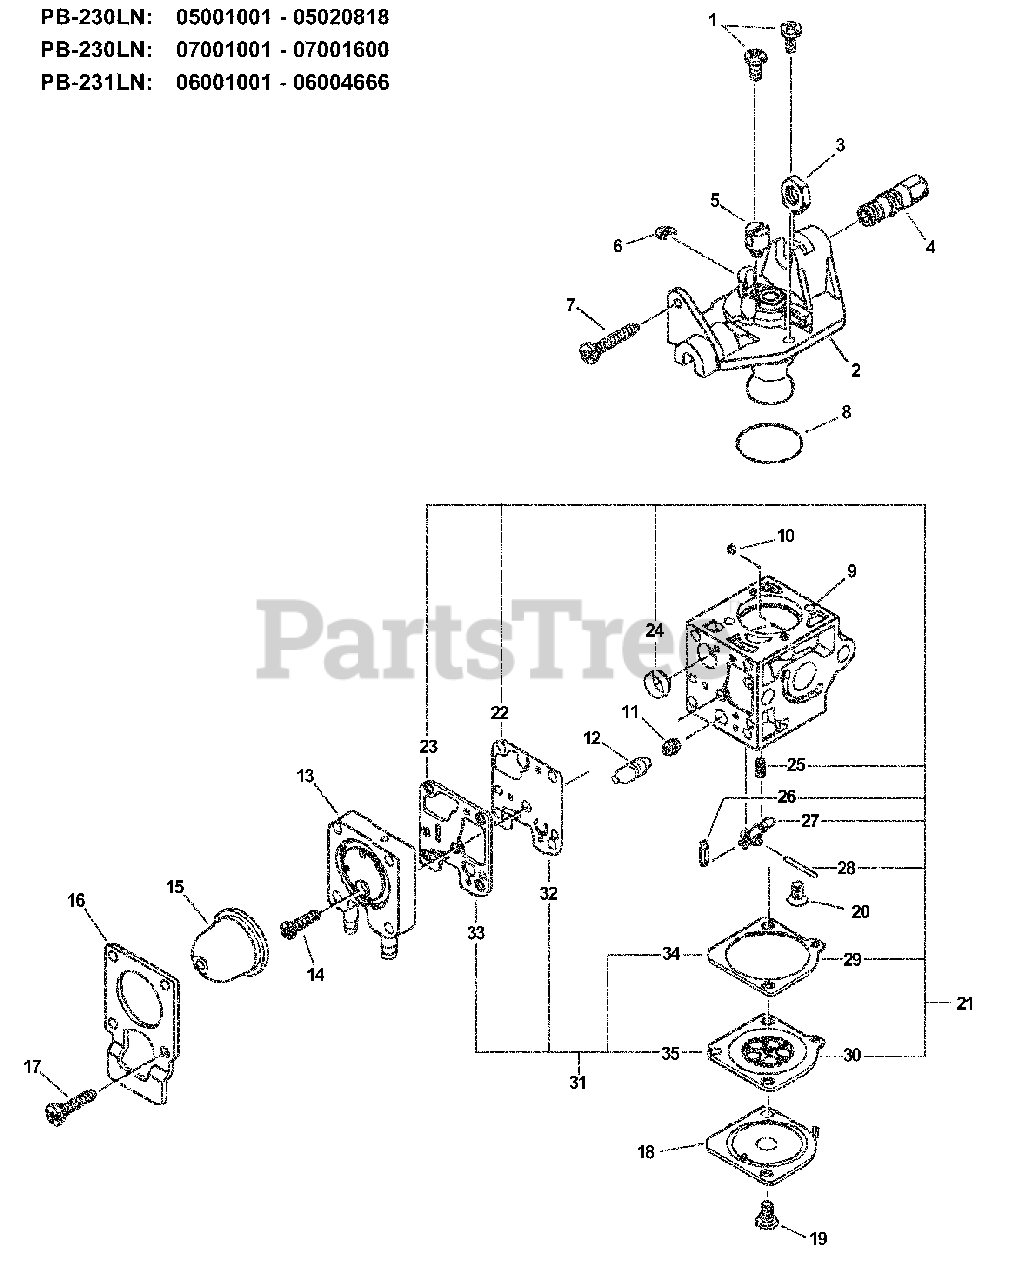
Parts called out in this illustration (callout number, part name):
2	ROTOR COVER ASSY
4	NUT, CABLE ADJUST
6	RING, RETAINING
7	SCREW, IDLE ADJUST
9	BODY, CARBURETOR
10	GUIDE, ROLLER
12	PLUG KIT
13	BASE, PURGE
14	SCREW, PURGE BASE
15	BULB, PURGE
16	RETAINER, PURGE BULB
17	SCREW, RETAINER
18	COVER, METERING
20	SCREW, METERING LEVER PIN
21	REPAIR KIT
22	DIAPHRAGM, PUMP
23	GASKET, PUMP
24	STRAINER
25	SPRING, METERING LEVER
26	VALVE, INLET NEEDLE
27	LEVER, METERING
28	PIN, METERING LEVER
29	GASKET, METERING
30	DIAPHRAGM, METERING
31	DIAPHRAGM/GASKET KIT
32	DIAPHRAGM, PUMP
33	GASKET, PUMP
34	GASKET, METERING
35	DIAPHRAGM, METERING
